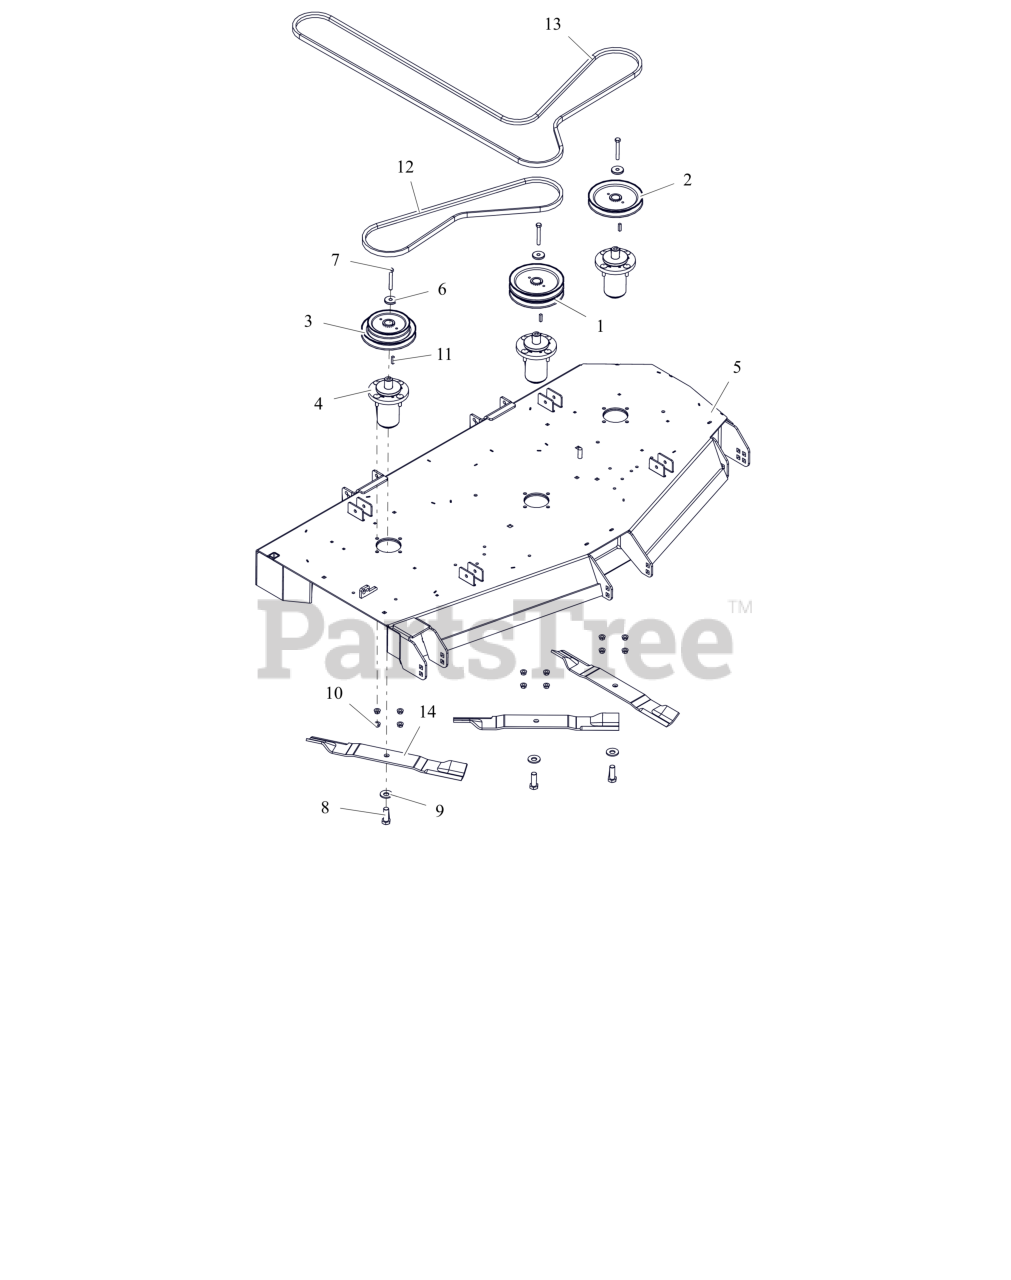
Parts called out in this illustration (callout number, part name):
1	PULLEY, DOUBLE 1.000 ID X 6.750 OD
2	PULLEY, V-1" ID X 6.75 OD
3	PULLEY, DBL-1"IDX6.75"&5.25"OD
4	ASM, MAINT FREE ALUM SPINDLE
5	WLDMT, 60" SIDE DISCH DECK (RED) W/ SAFETY DECALS
6	RETAINER, SHEAVE
7	BLT, HEX .38-16X2.75 G8 ZCC
8	BLT, HEX .62-18X1.75 G8 ZCC
9	WSHR-BLVL .669X1.535X.138
10	NUT-LK-CTR-FLG .375-16 GF ZCC
11	KEY, SQ .25X.25X1.00 RC 40-50
12	V-BELT, B-COGGED
13	BELT, B-SECTION EPDM RAW EDGE
14	BLADE, MOWER (20.50")
